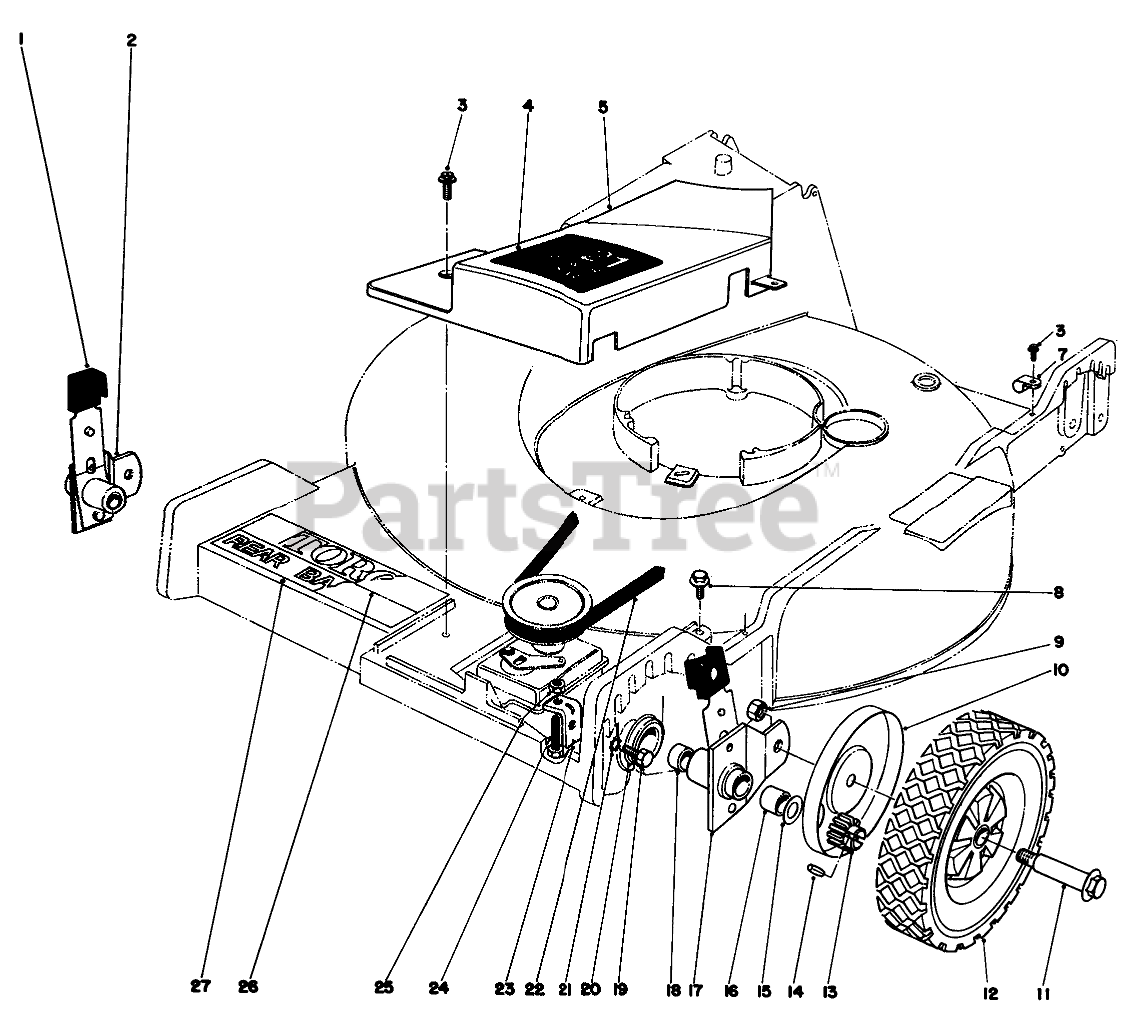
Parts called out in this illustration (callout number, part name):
1	KNOB-ARM
2	Pivot Arm R.H. (Incl. Ref. #16 & 18)
3	SCREW
4	Decal Belt Cover
5	BELT COVER
7	CLAMP-NYLON
8	SCREW-HWHTF
9	Nut
10	WHEEL COVER
11	BOLT-WHEEL
12	Wheel & Tire Assembly
13	Pinion
14	PIN-GROOVED
15	WASHER-THRUST
16	Bushing
17	Pivot Arm L.H. (Incl. Ref. #16 & 18)
18	Bushing
19	SCREW-HH
20	END CAP
21	WASHER-LOCK
22	V-BELT
23	Bracket-Gear Box
24	SCREW
25	NUT-LOCK
26	TORO LOGO DECAL
27	DECK DECAL
